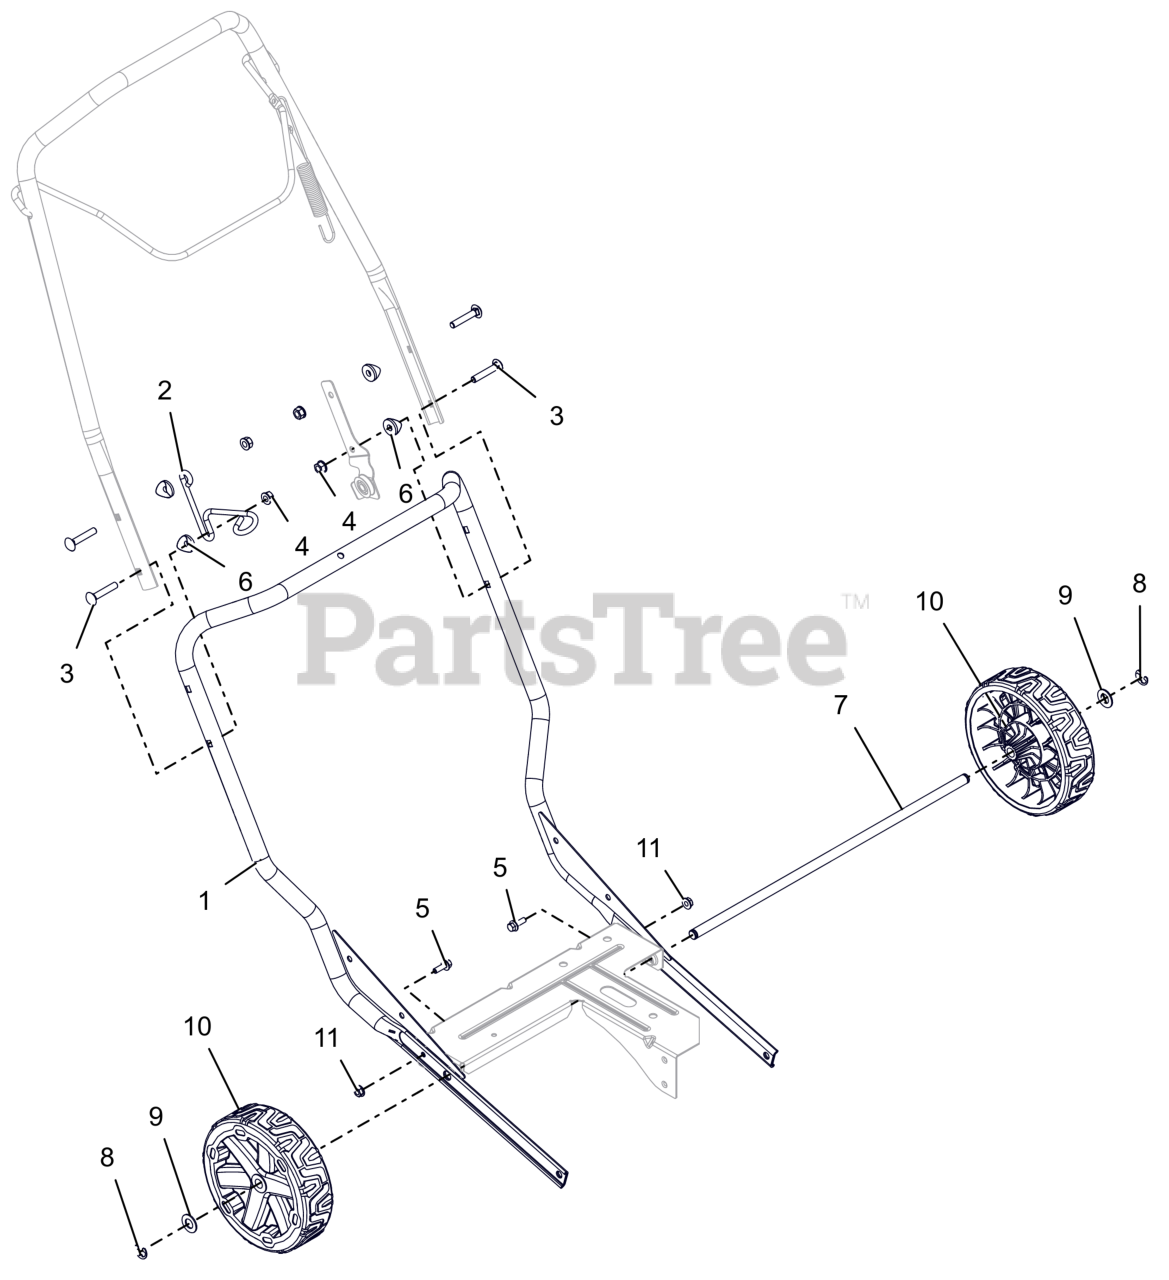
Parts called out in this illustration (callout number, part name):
1	HANDLEBAR, LOWER - W/DECAL
2	HOLDER, RECOIL
3	BLT, RHSN .31-18X1.75 G5 ZCC
4	NUT,LK-CTR-FLG .31-18 GF ZCC
5	BLT,HEX-FLG .25-20X.75 G5 ZCC
6	SPACER, HANDLEBAR (OD .875)
7	SHAFT, AXLE
8	RG-RTNG-EXT .500X.042 (E)
9	WSHR, FLT .531X1.00X.063 ZCC
10	TIRE/WHEEL- 7.5 X 2.0
11	NUT-LK-TOP-FLG .250-20 GF ZCC
